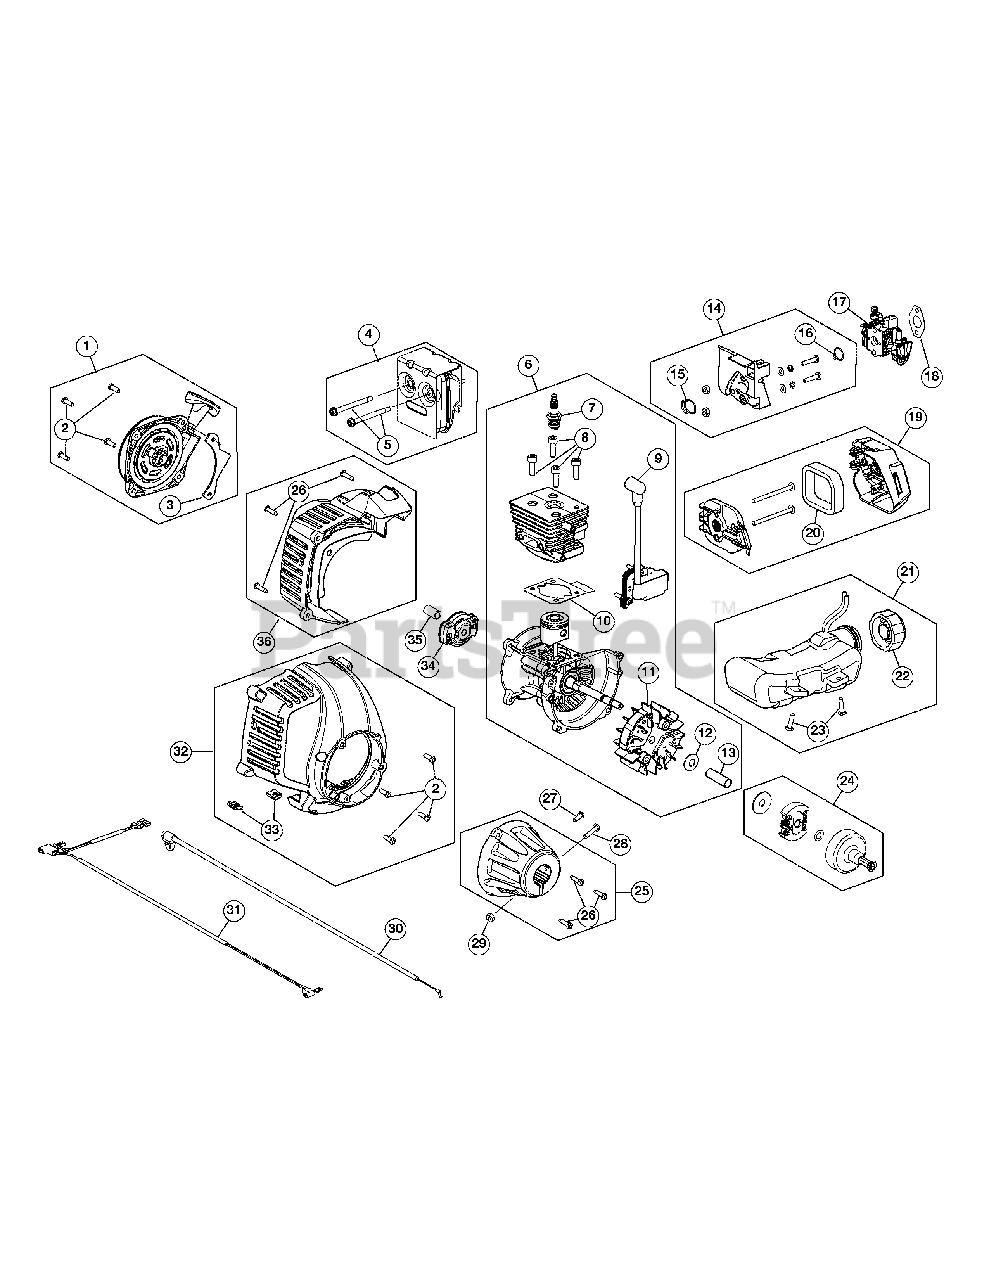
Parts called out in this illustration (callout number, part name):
1	Rear Cover Assembly (Incl. 2 & 3)
2	Starter Screw
3	Starter Assembly Guard (Incl. 2)
4	Muffler Assembly (Incl. 5)
5	Muffler Screws
6	Short Block Assembly
7	Spark Plug
8	Cylinder Bolt
9	Module Assembly
10	Cylinder Gasket
11	Flywheel Assembly
12	Washer
13	Spacer
14	Insulator Assembly (Incl. 15 & 16)
15	Insulator O-Ring
16	Carburetor O-Ring
17	Carburetor
18	Carburetor Gasket
19	Air Cleaner Assembly (Incl. 20)
20	Air Cleaner Filter
21	Fuel Tank Assembly (Incl. 22 & 23)
22	Fuel Tank Cap
23	Fuel Tank Screw
24	Clutch Assembly
25	Clutch Cover Assembly (Incl. 26)
26	Cover Screw
27	Anti-Rotation Screw
28	Clamp Screw
29	Clamp Nut
30	Throttle Cable
31	Lead Wires
32	Front Engine Cover Assembly (Incl. 2 & 33)
33	U-Shaped Nut
34	Pawl Assembly
35	Adapter
36	Rear Engine Cover Assembly (Incl. 26)
